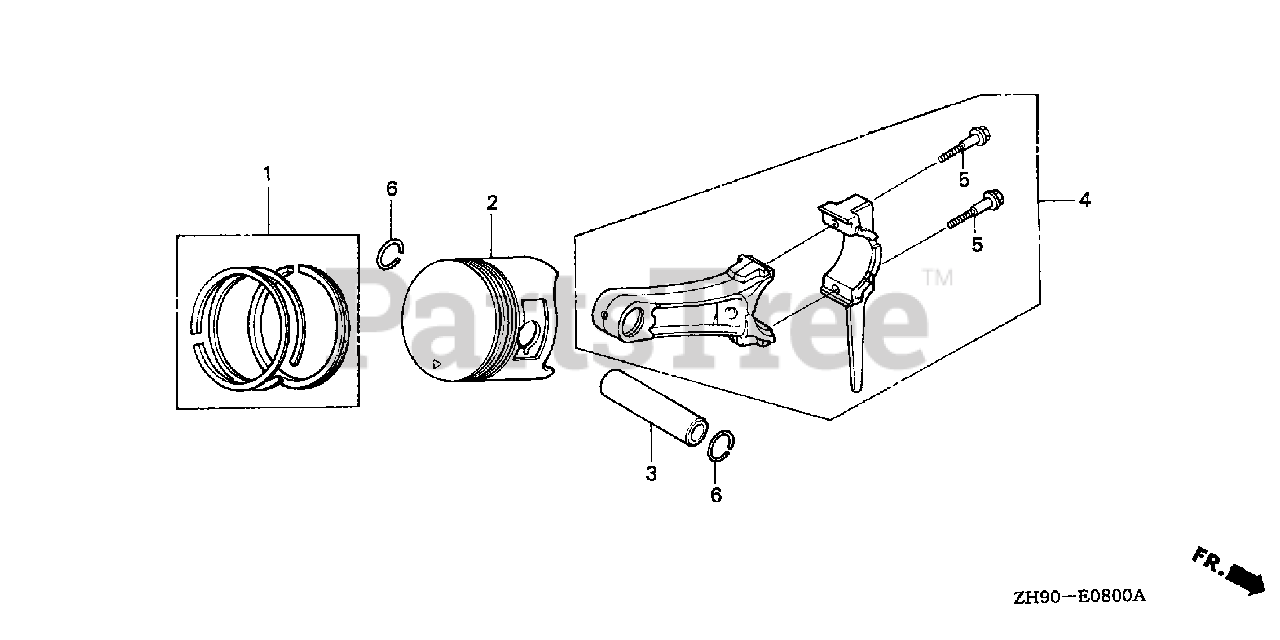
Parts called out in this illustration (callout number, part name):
1	RING SET, PISTON (STD)
1	RING SET, PISTON (OS 0.25)
1	RING SET, PISTON (OS 0.50)
1	RING SET, PISTON (0.75)
2	PISTON (STD)
2	PISTON (OS 0.25)
2	PISTON (OS 0.50)
2	PISTON (0.75)
3	PIN, PISTON
4	ROD ASSY., CONNECTING (STD)
4	ROD ASSY., CONNECTING (US 0.25)
5	BOLT, CONNECTING ROD
6	CLIP, PISTON PIN (18MM)
